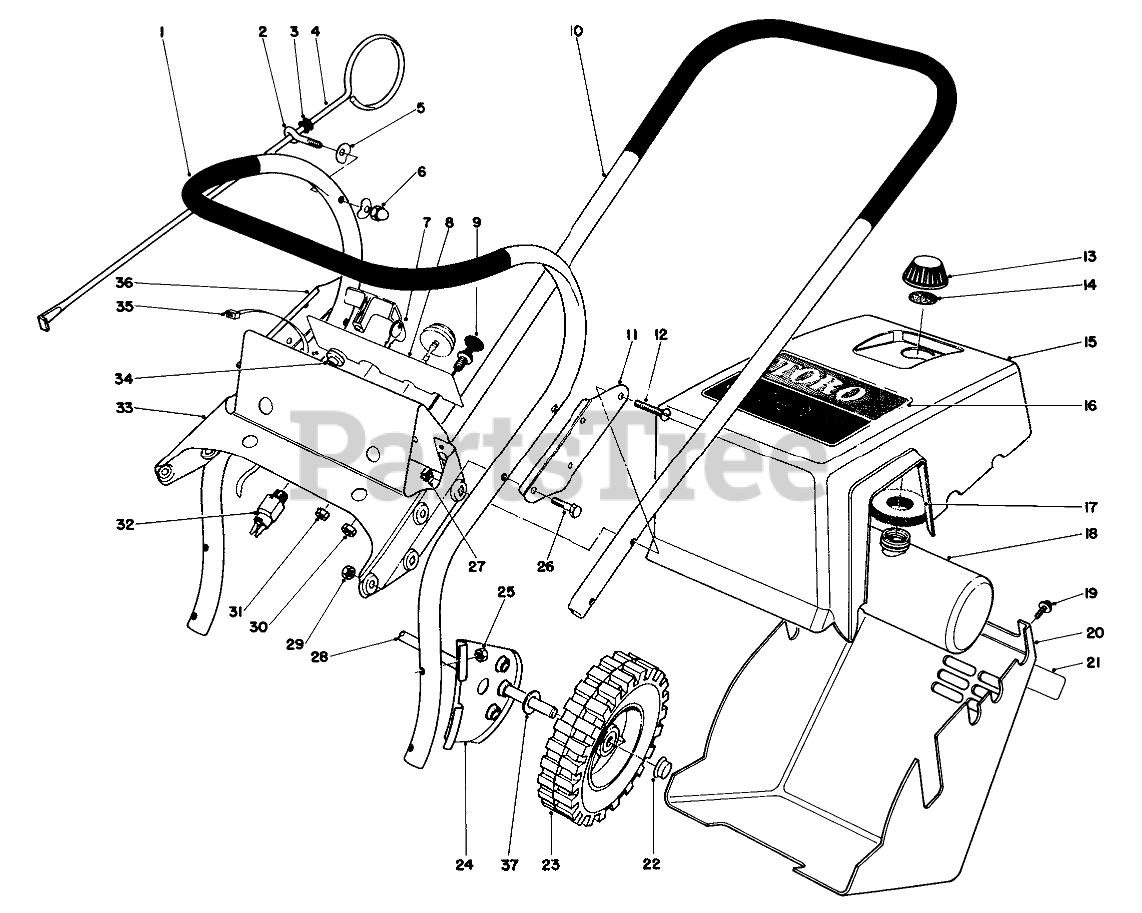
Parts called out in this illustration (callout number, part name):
1	LOWER HANDLE
2	Bolt-Eye
3	GROMMET
4	Vane Adj. Rod
5	WASHER
6	NUT-CAP
7	Key
8	CONTROL PANEL DECAL
9	CHOKE CONTROL
10	Upper Handle
11	SPLICE PLATE
12	Sems Mach. Screw
13	Gas Cap Assy. (Incl.Ref. #14)
14	GAS CAP GASKET
15	Shroud (Incl. Ref. #16)
16	Decal-Toro
17	FOAM PAD
18	Gas Tank Assembly (Incl. Ref. #13 & 14)
19	SCREW
20	Lower Shroud (Incl. Ref. #21)
21	Decal-Instruction
22	RETAINER-PUSH ON
23	WHEEL
24	WHEEL BRKT B
25	NUT-HEX
26	SCREW-HH
27	Nut Retainer
29	NUT-LOCK, CONE
30	PAL NUT/CHOKE CNTRL
31	NUT-KEPS
32	SWITCH-ON / OFF
33	Tank Support & Control Panel (Incl. Ref. #8)
34	GUIDE-ROPE, STARTER
35	Strap
36	Plate-Splice
37	WASHER-FLAT
